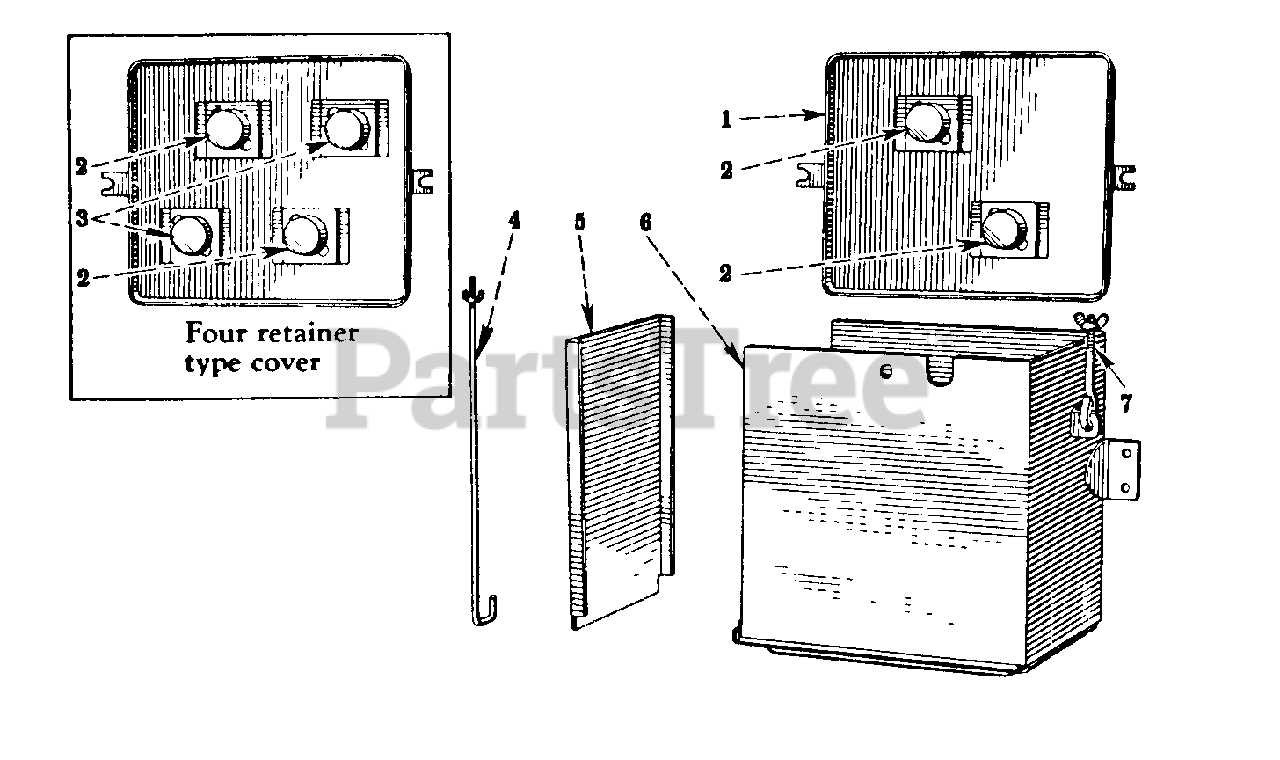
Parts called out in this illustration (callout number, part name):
1	COVER ASSY, BATTERY BOX
2	RUBBER, BATTERY HOLD-DOWN - LONG
3	RUBBER, BATTERY HOLD-DOWN - SHORT
4	SCREW, BATTERY BOX - FRONT
5	COVER BATTERY BOX FRONT
6	BOX, BATTERY
7	SCREW, BATTERY BOX - REAR
